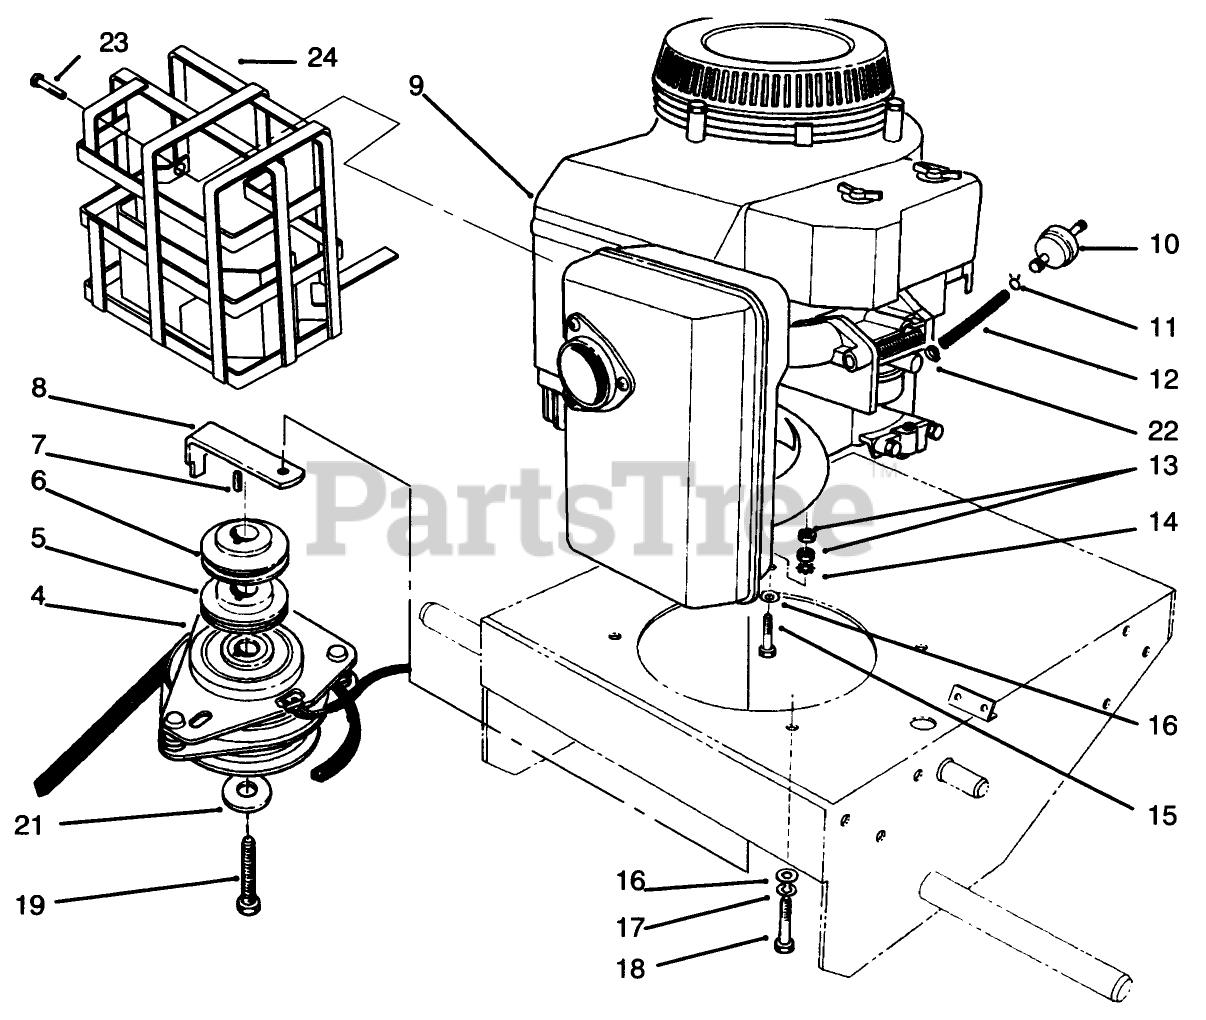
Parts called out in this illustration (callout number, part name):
5	SHEAVE-HALF, LOWER
6	SHEAVE-HALF, UPPER
7	KEY-SQUARE
10	FILTER-FUEL
11	CLAMP-HOSE
13	NUT-JAM
14	WASHER-LOCK
15	SCREW
16	WASHER-PLAIN
17	WASHER-LOCK
19	SCREW-CLUTCH
21	WASHER
22	CLAMP-WORM
23	Screw-Hex. Hd. (Engine)
